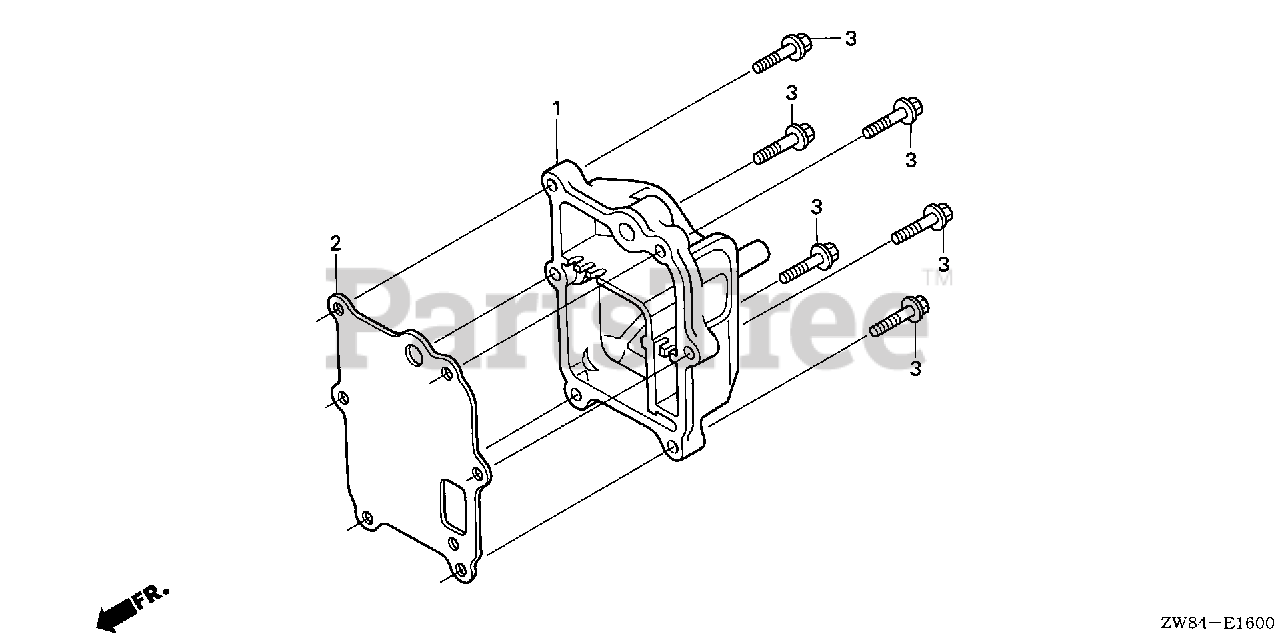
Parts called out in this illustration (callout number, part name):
1	COVER, EX. CHAMBER
2	GASKET, EX. CHAMBER
3	BOLT, FLANGE (6X23)
